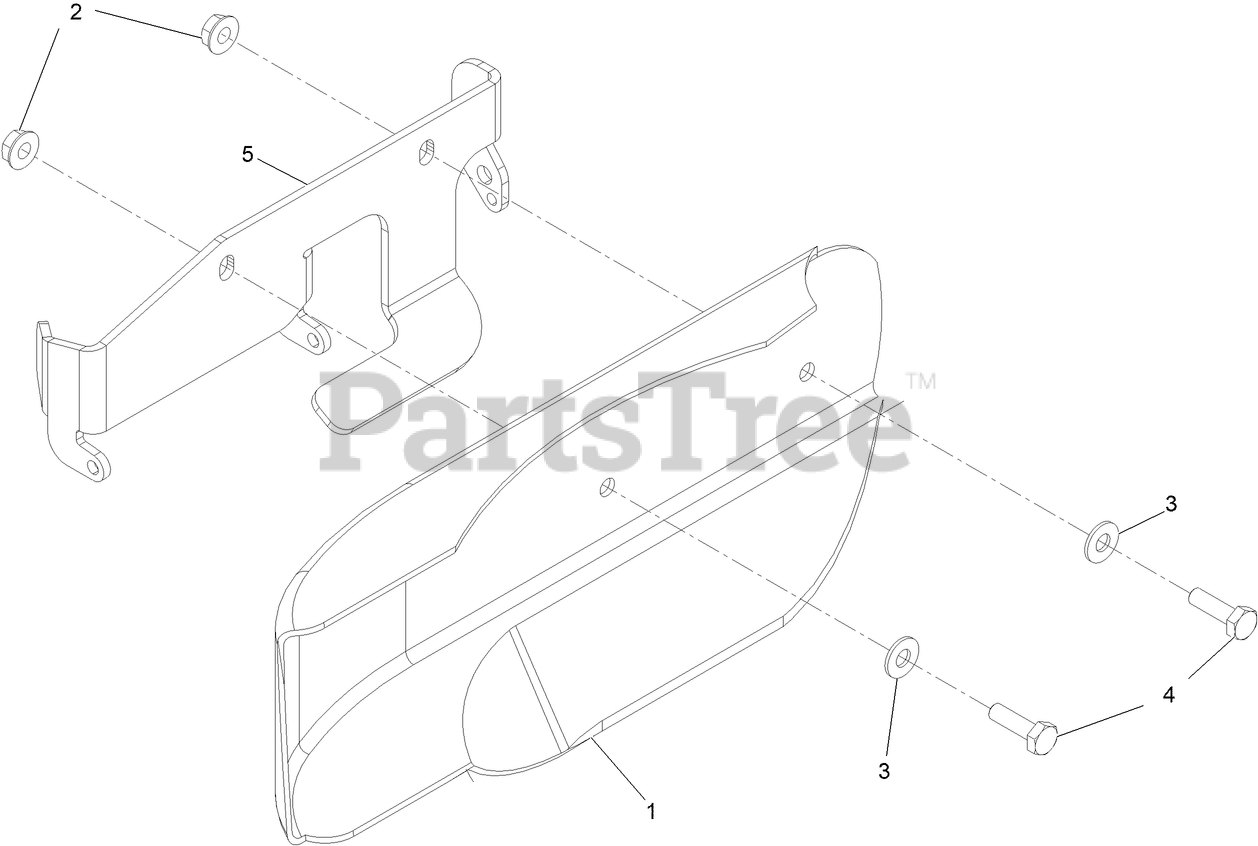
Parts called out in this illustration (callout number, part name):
1	Screw-HH 1/4-20 X 7/8 SS
2	BRACKET-DEFLECTOR, SIDE
3	WASHER-FLAT
4	SCREW-HH
